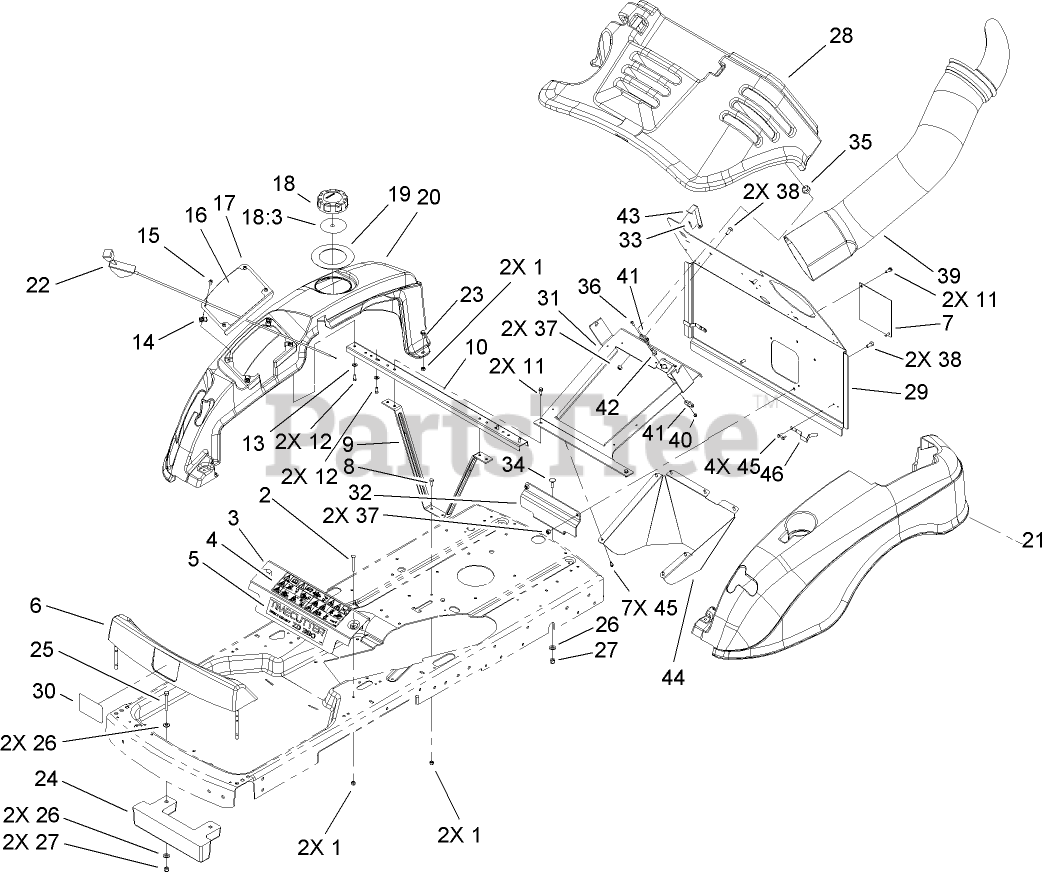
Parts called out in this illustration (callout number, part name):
1	NUT-LOCK, NI
2	SCREW-CARR
3	BRACKET-SUPPORT, FRONT
4	DECAL-DANGER
6	FOOTREST ASM
7	DOOR-PLUG ACCESS
8	SCREW-HH
9	BRACE ASM
10	CHANNEL-CROSS
11	SCREW-HWH, THREAD ROLL
12	SCREW-PLASTITE
13	WASHER-FLAT
15	SCREW-PRH
16	DECAL-CONTROL
17	PANEL-CONTROL
18	GAS CAP ASM
18:3	GASKET-CAP, GAS
19	SEAL-RUBBER
20	COVER-SIDE, RH
21	COVER-SIDE, LH
22	CABLE-THROTTLE
23	SCREW-SHOULDER
24	WEIGHT-BAGGER
25	SCREW-HH
26	WASHER-FLAT
27	NUT-LOCK, NI
28	COVER-ENGINE
31	HINGE-OFFSET
32	BRACKET-HITCH
33	PIN-COTTER
34	SCREW-CARR
35	GROMMET
36	SCREW-HSBH
37	NUT-LOCK, NI
38	SCREW-HH
39	TUBE-DISCHARGE
40	NUT-LOCK, NI
42	PIN-HOOD
43	TAB-SWITCH
44	DUCT - ENGINE
45	SCREW-TAPTITE
46	CLIP - RETAINER
